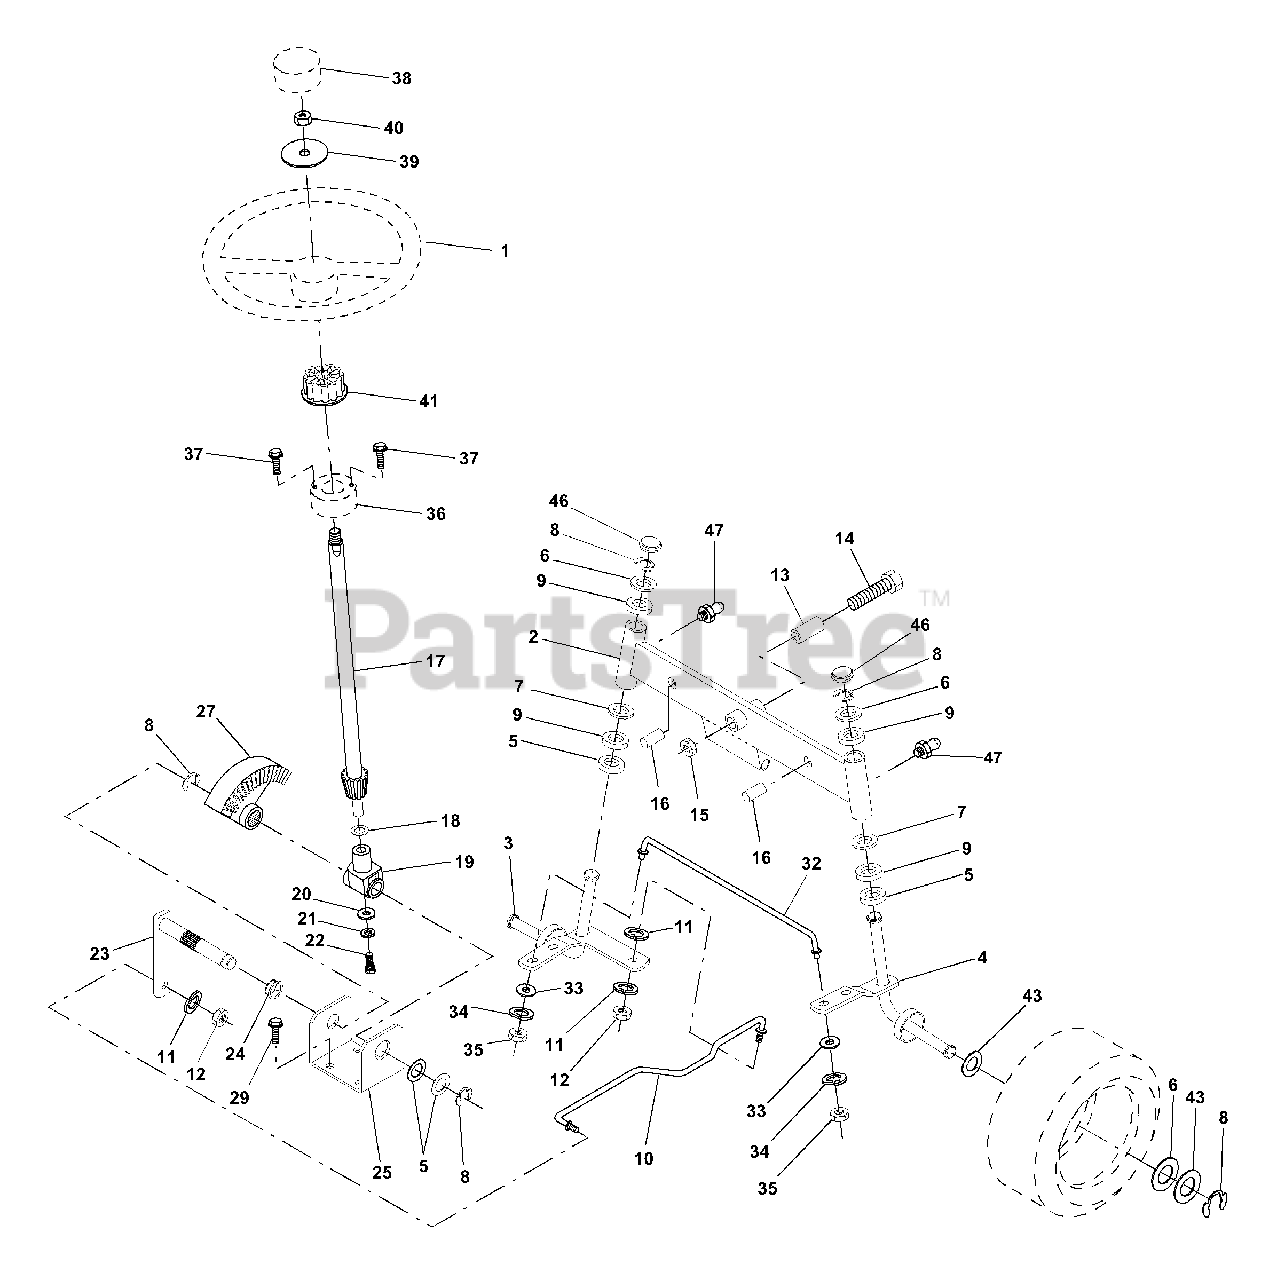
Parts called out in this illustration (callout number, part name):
1	Wheel Steering Auto Grey
2	Axle Asm Fr LT W/gzks 38/42
3	Spindle Asm LH
4	Spindle Asm RH
5	Bearing Race Thrust Harden
6	Washer 25/32 X 1-5/8 X 16 Ga
7	Washer 27/32 X 1-1/4 X 16 Ga
8	Ring Klip #t5304-75
9	Bearing Col Strg Blk
10	Link Drag Sol Ball Jt 20 064
11	Washer Lock Hvy Hlcl Spr 3/8
12	Nut Fin Hex 3/8-24 Unf
13	Spacer Bearing Axle Front
14	Bolt Hex 5/8-11 Unc X 3-1/2
15	Nut Lock Flange 5/8-11 Unc
16	Pin Axle 5/8 X 1 55/1 54 Lg
17	Shaft Asm Strg 20 31 x 3/4 YP YT
18	Washer Thrust 515x 750x 033
19	Support Shaft
20	Washer Shim 1/4 X 5/8 X 062
21	Washer Lock Hvy Helical 1/4
22	Screw Hex Socket 1/4-20 X 5/8
23	Shaft Asm Pittman
24	Nyliner Snap In
25	Bracket Steering
27	Gear Sector
29	Screw Thdrol 3/8-16x3/4 Ty-tt
32	Rod Tie Wire Form 19 75 Elec
33	Washer 11/32 x 3/4 x 16 Ga.
34	Washer, Lock Hvy Hlcl Spr 5/16
35	Locknut 5/16-24 Unf
36	Bushing Strg Blk 742/747 Id
37	Screw Slftp #10-16 X 1/2 Ty-b
38	Insert Cap Strg Wh Aut Hus Gry
39	Washer 53 X 2 25 X 160 Zinc
40	Nut Hex Jam Toplock 1/2-20 Unf
41	Adapter Wheel Strg 758/ 753id
43	Washer 25/32 X 1 1/4 X 16 Ga
44	Washer 25/32 X 1-5/8 X 16 Ga
45	Ring Klip #t5304-75
46	Cap Spindle Fr Top Blk
47	Fitting Grease
